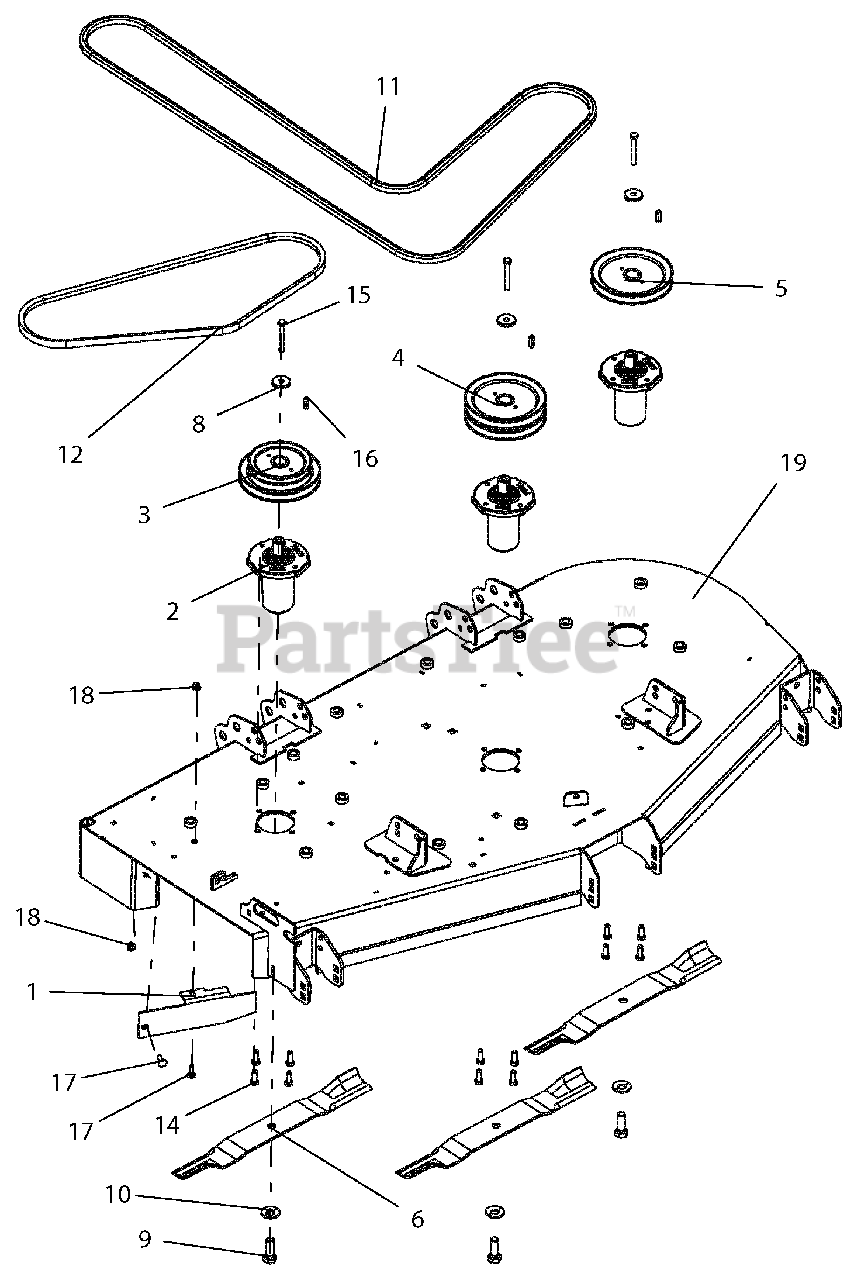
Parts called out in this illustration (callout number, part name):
1	BAFFLE, DISCHARGE, 60"-RED
2	SERVICE, ASM SPINDLE- DUCTILE
3	PULLEY, DOUBLE -1" ID X 6.75" & 5.25" OD
4	PULLEY, DOUBLE 1"ID X 6.75"OD-BLACK
5	PULLEY, V-1" ID X 6.75" OD-BLACK
6	BLADE, 20.5"
8	RETAINER, SHEAVE SPINDLE
9	BLT, HEX .62-18X1.75 GR8 YWZC
10	WSHR, BLVL .63X1.625X.14
11	BELT, BB 118.00 WRAPPED HEX
12	BELT, B 63.00 RAW COGGED
14	BLT-HEX .38-16X1.00 GR5 YWZC EP30
15	BLT-HEX .38-16X2.75 GR8 YWZC
16	KEY-SQ .250X.250X1.00 RC 40-50
17	BLT-RDHDSQSHNK .31-18X1.00 G5 Y
18	NUT-LK-NYL-FLG .31-18 YWZC
19	KIT, DECK - 60" W/SAFTEY DECALS
